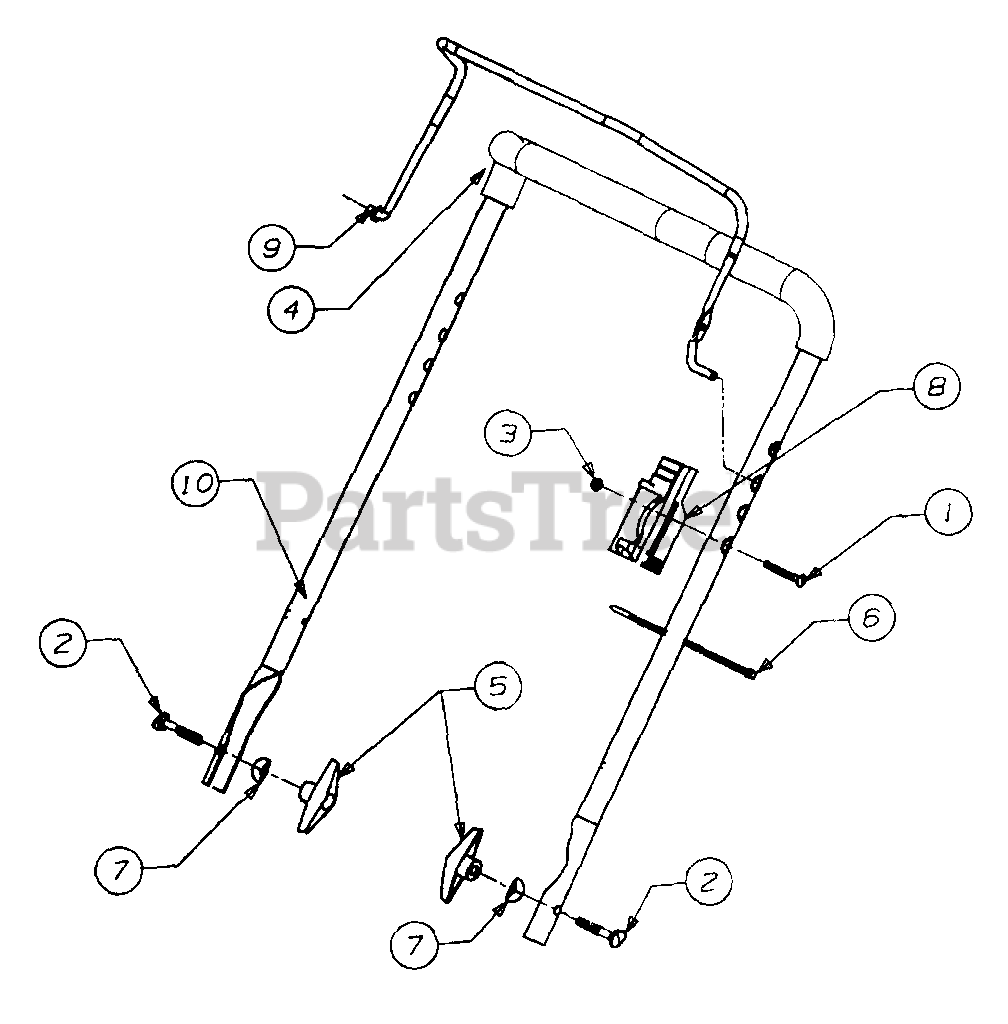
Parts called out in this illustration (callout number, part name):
1	Screw - Oval C-Sink L
2	Bolt - Carriage
3	Nut Insul. Lock
4	Grip Foam
5	Knob Handle
6	Tie Cable
7	Washer Saddle
8	Body - Lever Control
